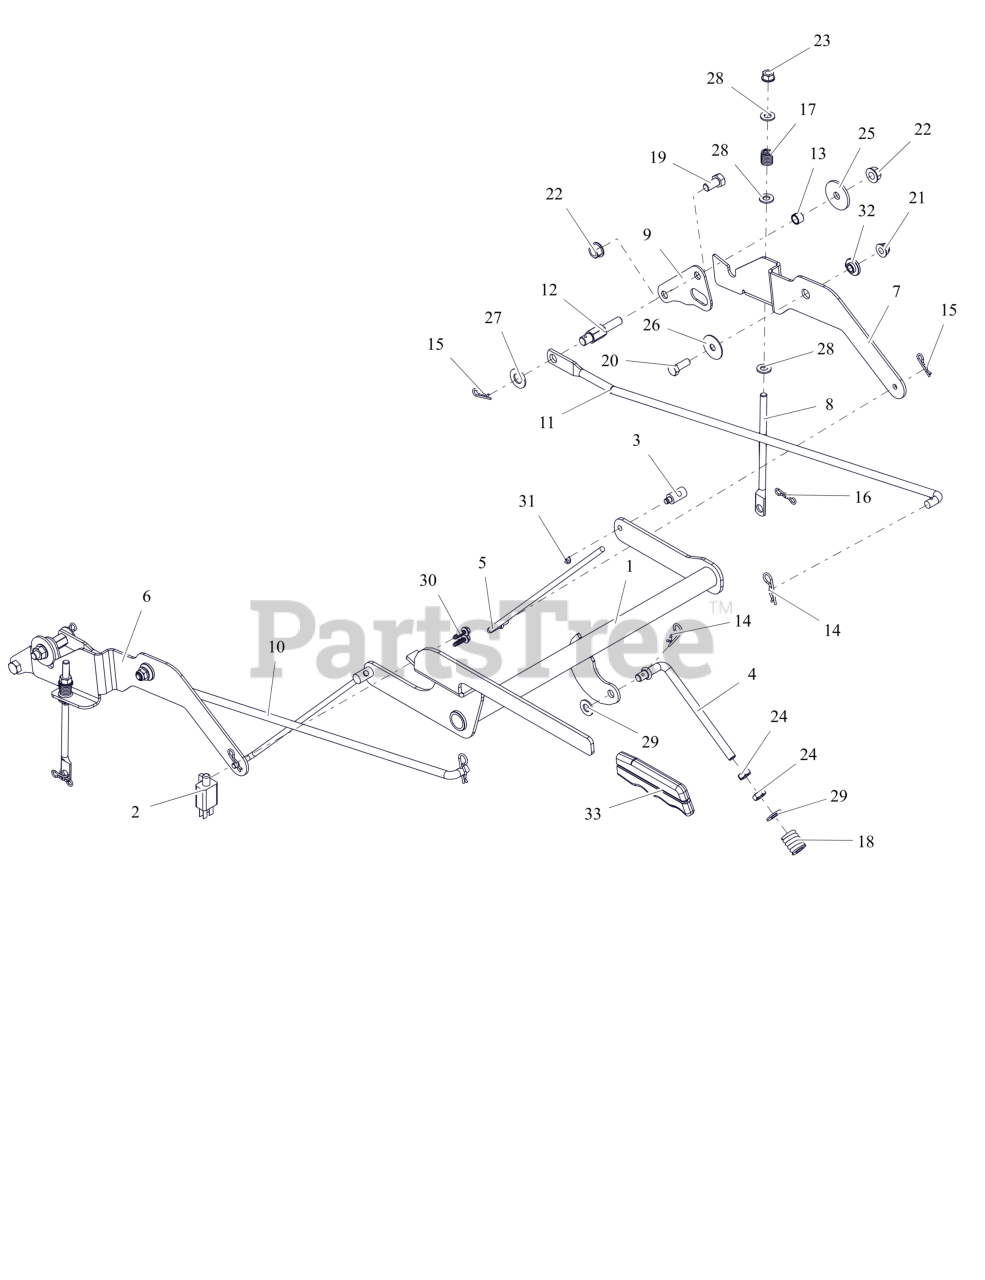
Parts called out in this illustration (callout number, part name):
1	WLDMT, BRAKE LEVER
2	SWITCH- DOUBLE POLE N.O./N.O.
3	TRUNION, 1/4-20
4	LINK, OVER CENTER, PARKING BRK
5	LINK, BRAKE ARM
6	INTERLOCK, RH BRAKE LINK
7	INTERLOCK, LH BRAKE LINK
8	LINK, BRAKE COG
9	PLATE, TRANSAXLE ADAPTOR
10	LINKAGE, STEERING - RH
11	LINKAGE, STEERING - LH
12	POST, STEERING LINK MOUNTING
13	SPCR, SLV .385X.500X.350
14	PIN, HAIR #203 .09X1.50 ZCC
15	PIN, HAIR #213 .08X1.19 ZCC
16	PIN, BOWTIE #72 ZCC
17	SPRING, COMPRESSION
18	SG-COMP .187X.56X1.62
19	BLT,HEX .38-16X.75 G5 ZCC
20	BLT, HEX .31-18X.875 G5 ZCC
21	NUT,LK-NYL-FLG .31-18 G5ZC120
22	NUT-LK-CTR-FLG .375-16 GF ZCC
23	NUT,LK-CTR-FLG .31-18 GF ZCC
24	NUT-JAM .375-16 G2 ZCC
25	WSHR, FLT .380X1.50X.125 ZCC
26	WSHR, FLT .347X1.254X.048 ZCC
27	WSHR, FLT .505X1.00X.062 ZCC
28	WSHR,FLT .344X.688X.065 ZCC
29	WSHR,FLT .406X.812X.065 ZCC
30	SCR, PLASTITE #12X.75 ZCC
31	RG-RTNG-EXT .250X.025
32	BSHG, FLG .325X.499X.26X.88
33	GRIP, PARKING BRAKE (GREY)
